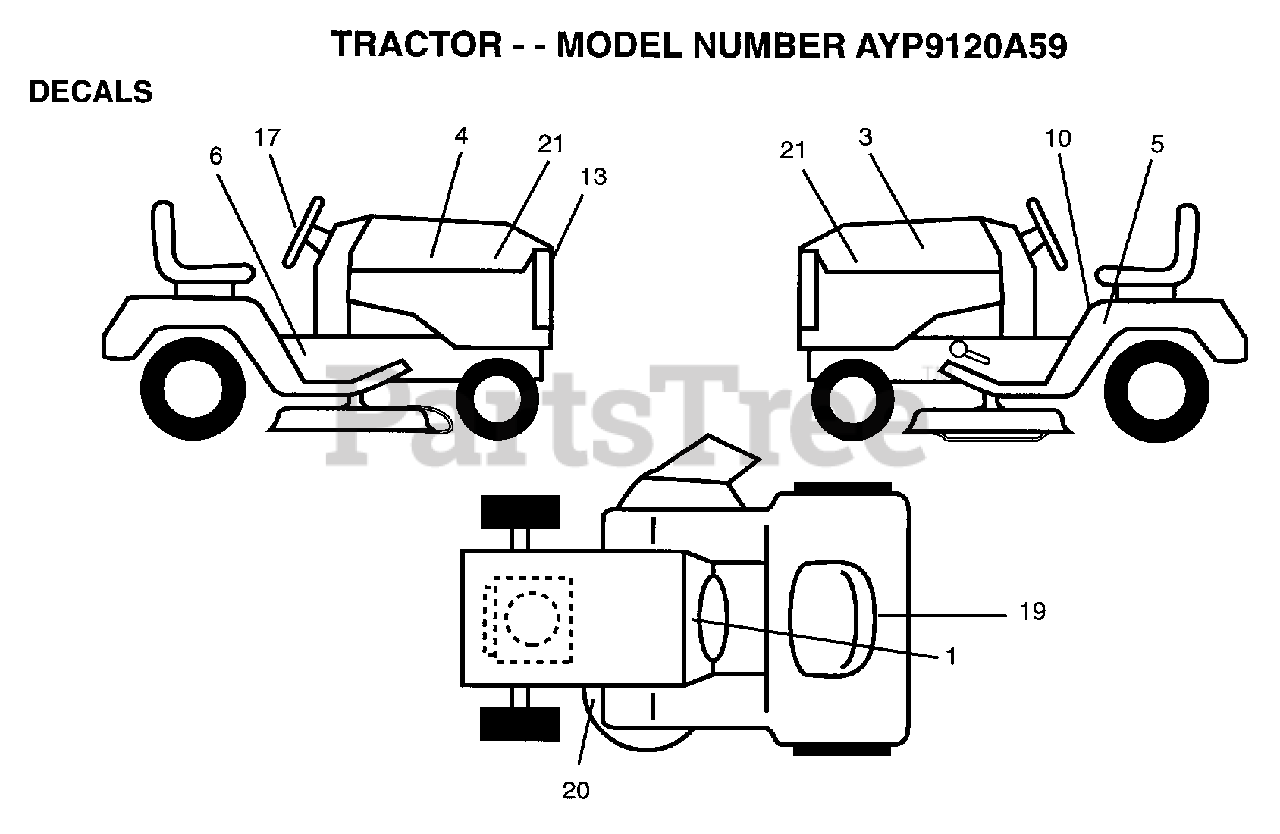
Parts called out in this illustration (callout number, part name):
1	DECAL.INST.OPER
3	DECAL STRIPE HOOD
4	DECAL STRIPE HOOD
5	DECAL
6	DECAL STRIPE HOOD
10	DECAL
13	DECAL.GRILLE
20	DECAL
21	DECAL.INST.HD.WIZ
